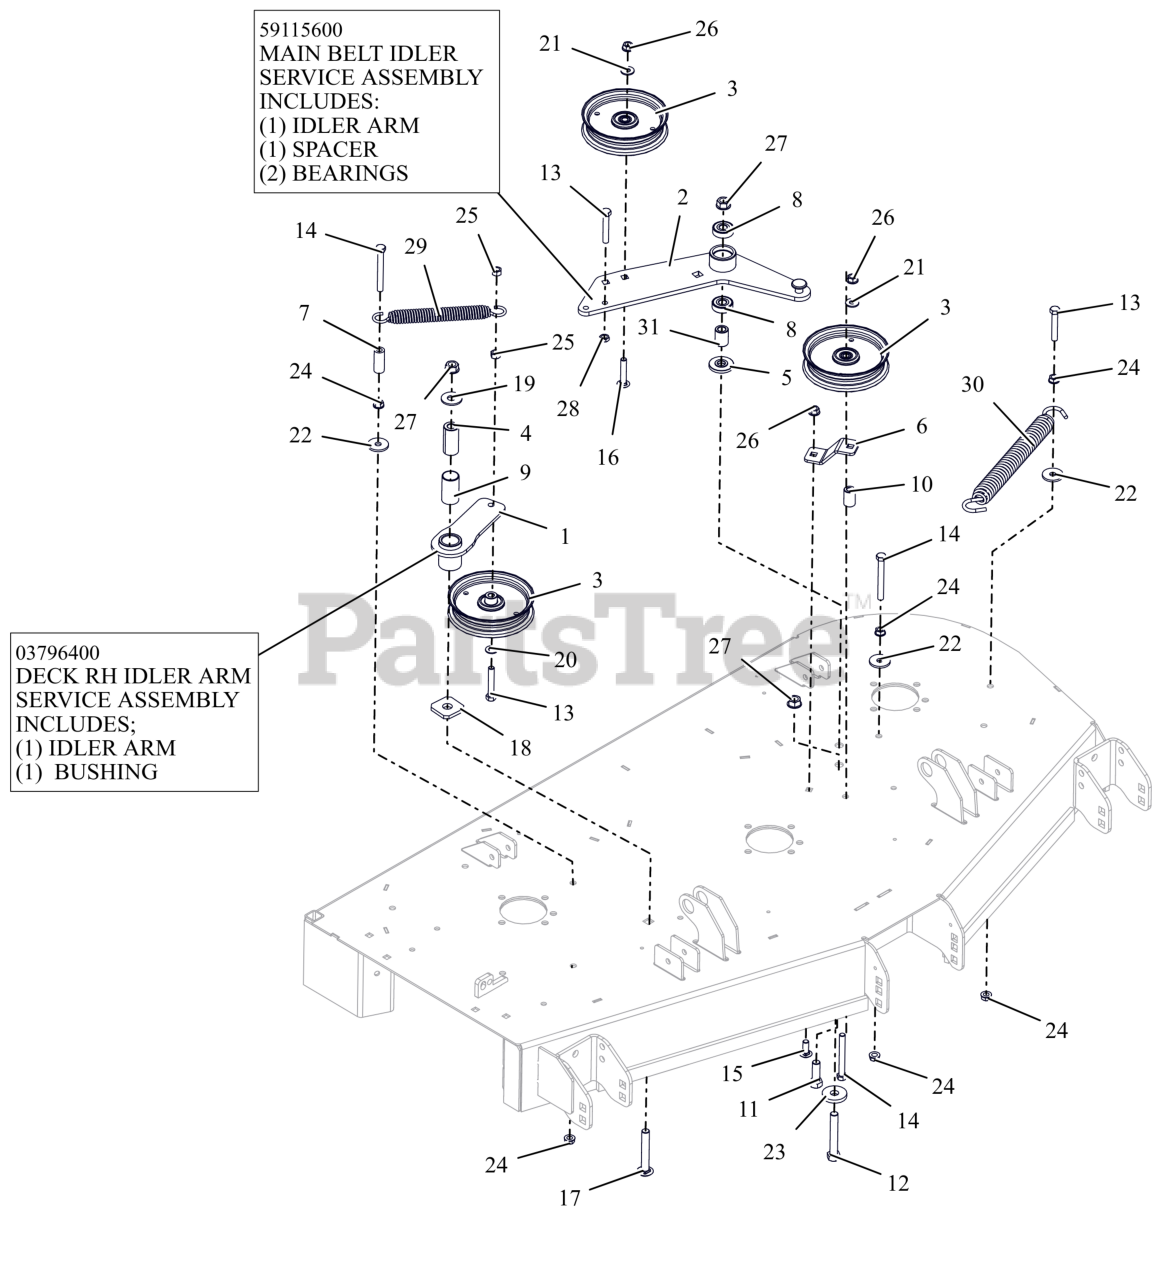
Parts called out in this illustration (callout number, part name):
1	WMT, IDLER ARM - BLACK
1	ASM, IDLER ARM (DECK)
2	WLDMT, DECK PTO IDLR ARM
2	ASSEMBLY, MAIN BELT IDLER
3	IDLER- FLAT - 5.00" X .75"
4	BSHG, SPCR .502X.997X2.03 PM
5	SPACER, IDLER ARM
6	PTO FIXED IDLER MTG BRKT-ORG
7	HOSE, .38 X 1.65
8	BRG-BALL .500X1.38X.437
9	BSHG, 1.00X1.125X1.937
10	BUSHING, SLV .380X.750X1.190
11	BLT,HEX .50-13X1.50 G5 ZCC
12	BLT,HEX .50-13X3.25 G5 ZCC
13	BLT,HEX .38-16X2.25 G5 ZCC
14	BLT, HEX .38-16X3.25 G5 ZCC
15	BLT,RHSSN .38-16X1.00 G5 ZCC
16	BLT,RHSSN.375-16X2.00 G5 ZCC
17	BTL,RHSSN .500-13 X 3.25 G5 ZCC
18	WSHR-FLT .640X1.75X.250
19	WSHR,FLT .563X1.375X.109 ZCC
20	WSHR,FLT .406X.812X.065 ZCC
21	WSHR,FLT .375X.875X.083 ZCC
22	WSHR,FLT .406X1.375X.135 ZCC
23	WSHR-FL-STL 0.557X1.625X0.25 ZCC
24	NUT, SPNLK-FLG .38-16 G5 ZCC
25	NUT-LK-CTR .38-16 ZC120
26	NUT-LK-CTR-FLG .375-16 GF ZCC
27	NUT-LK-CTR-FLG .500-13 GG ZCC
28	NUT-JAM .375-16 G2 ZCC
29	SPRING- EXTENSION
30	SPRING, EXTENSION
31	SPACER .510 X .867 X 1.1485
